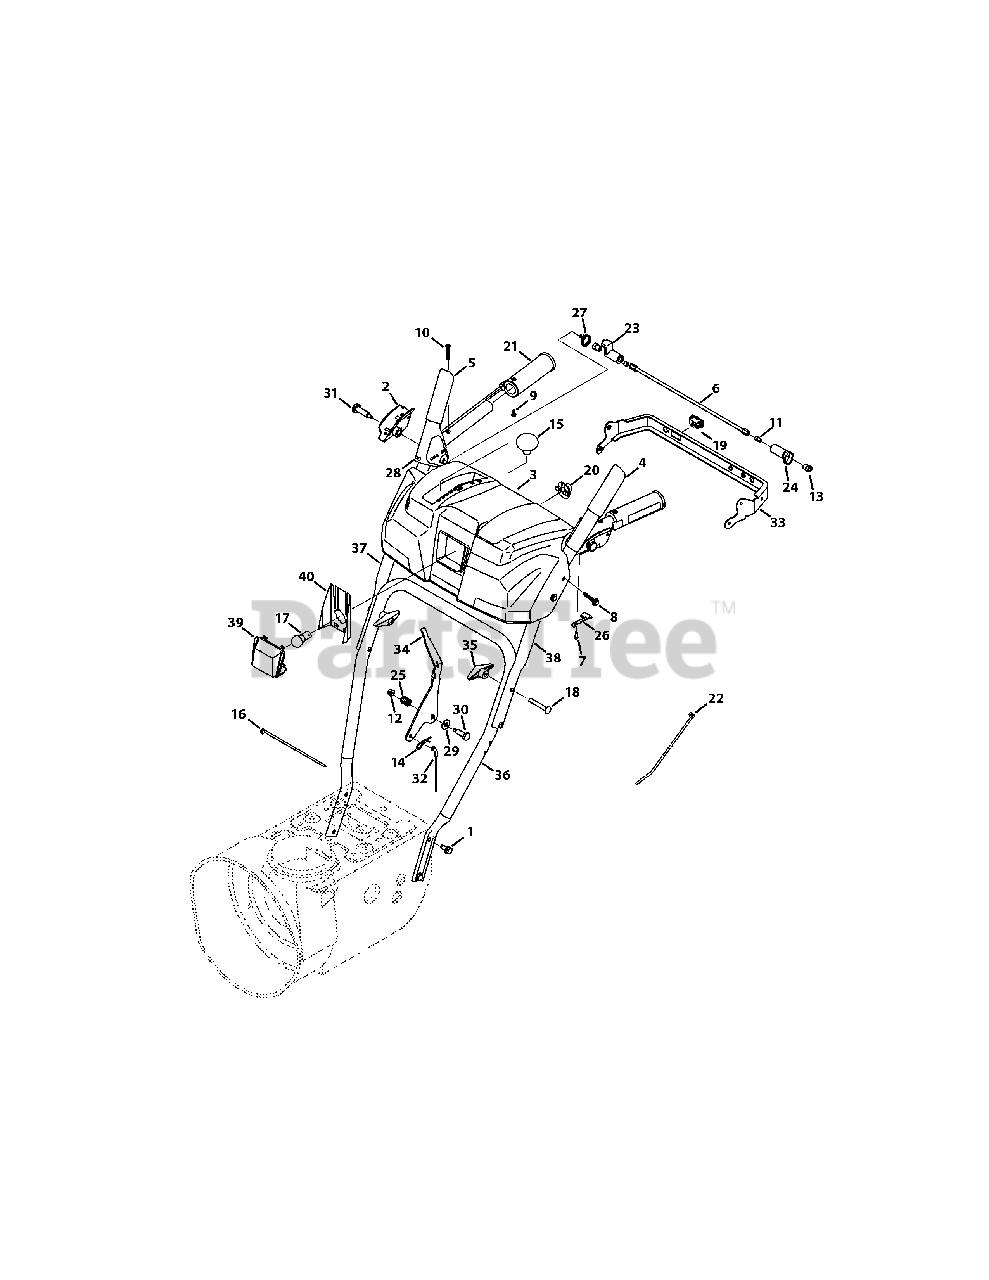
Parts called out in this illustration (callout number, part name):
1	Screw, Taptite, 5/16-18 x .750
2	Clutch Lock, RH
2	Clutch Lock, LH
3	Handle Panel w/ Light
3	Handle Panel w/o Light
4	Auger Engage
5	Drive Engage
7	Screw, Plastite, 8-16 x .50
8	Screw, Taptite, 1/4-20 x 1.625
9	Screw, 10-16 x 0.625
10	Screw, 10-24 x 1.375
11	Screw, 1/4-20 x .50
12	Nut, Flange Lock, 1/4-20
13	Nut, Hex, 1/4-20
14	Click Pin, .092 x 1.64
15	Shift Knob
16	Cable Tie, 7"
17	Lamp, 12.8V
18	Screw, Carriage, 5/16-48 x 2.25
19	Heated Grip Switch
20	Lamp Socket
21	Heated Grip
22	Cable Tie, Push Mount
23	Plate, Lock
24	Cam, Clutch Lock
25	Compression Spring, .39 x .60 x .88
26	Clutch Lock Spring
27	Torsion Spring, 0.8156 x .3038
28	Rubber Bumper
29	Washer, Flat, .385 x .87
30	Screw, Shield, .374 x 1.05
31	Screw, Shoulder, .437 x 1.345 x 1/4-20
32	Speed Selector Cable
33	Panel Bracket
34	Shift Lever
35	Wing Knob
36	Lower Handle
37	Upper RH Handle
38	Upper LH Handle
39	Lens Panel, Troy-Bilt
40	Lens Label, Troy-Bilt
